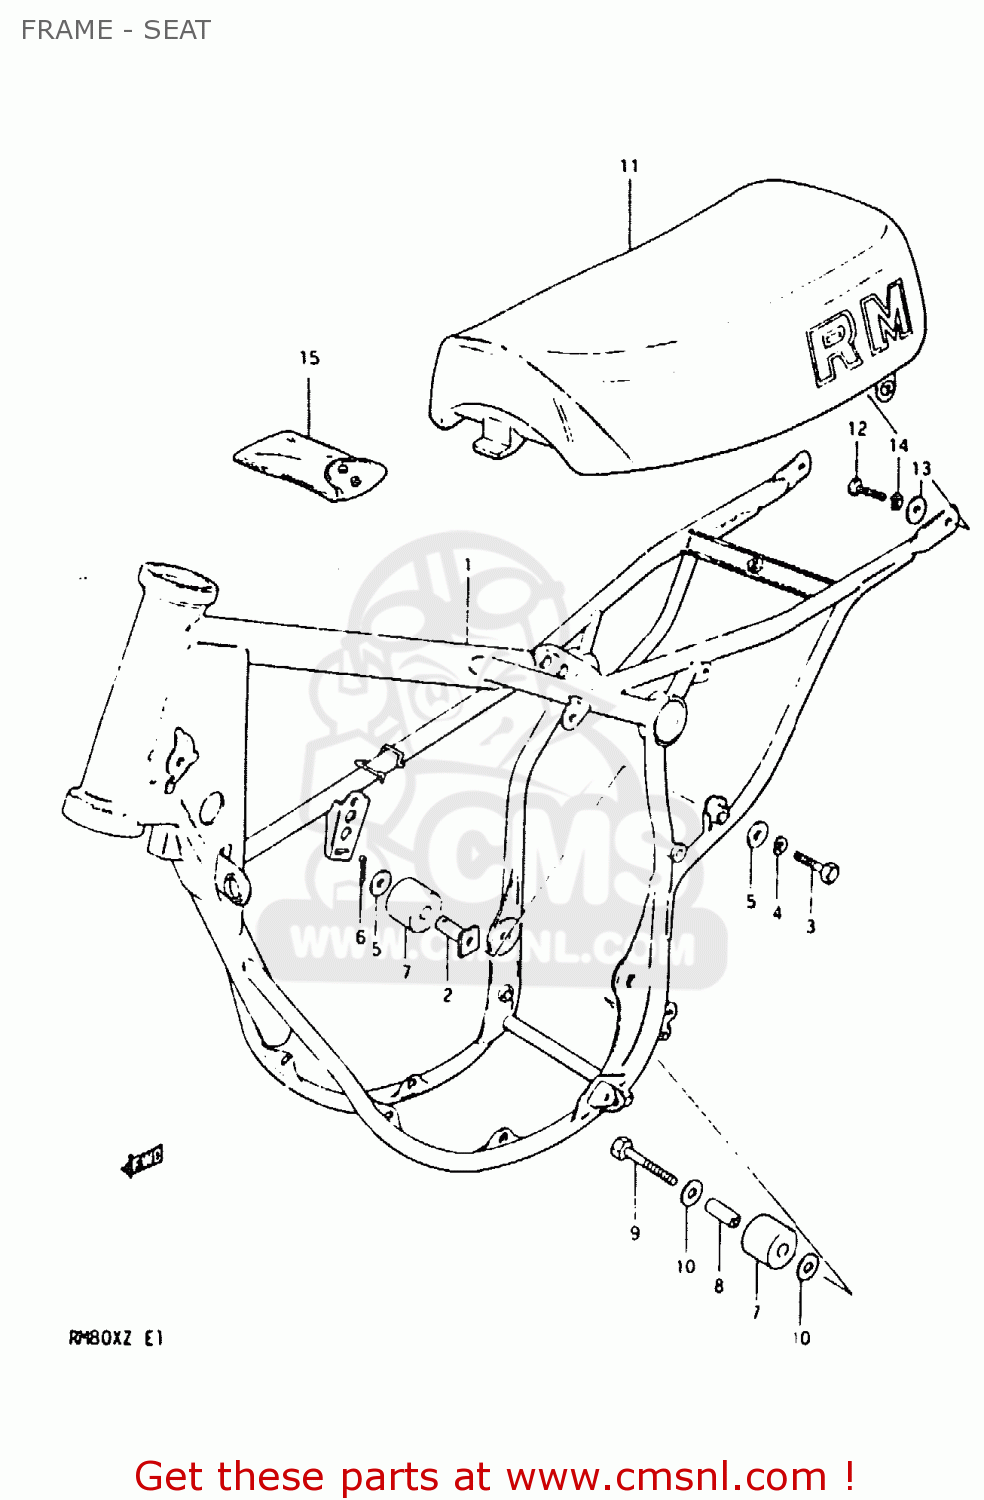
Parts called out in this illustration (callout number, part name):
1	FRAME
2	BOSS,CHAIN CONTROL
3	BOLT
4	LOCK WASHER
5	WASHER
6	PIN 25X20
7	ROLLER,CHAIN LENGTH CONTROLLER
8	SPACER (6.5X10.5X29)
9	BOLT 6X40
10	WASHER
11	SEAT ASSEMBLY
12	BOLT
13	WASHER
14	LOCK WASHER
15	TOOL SET
